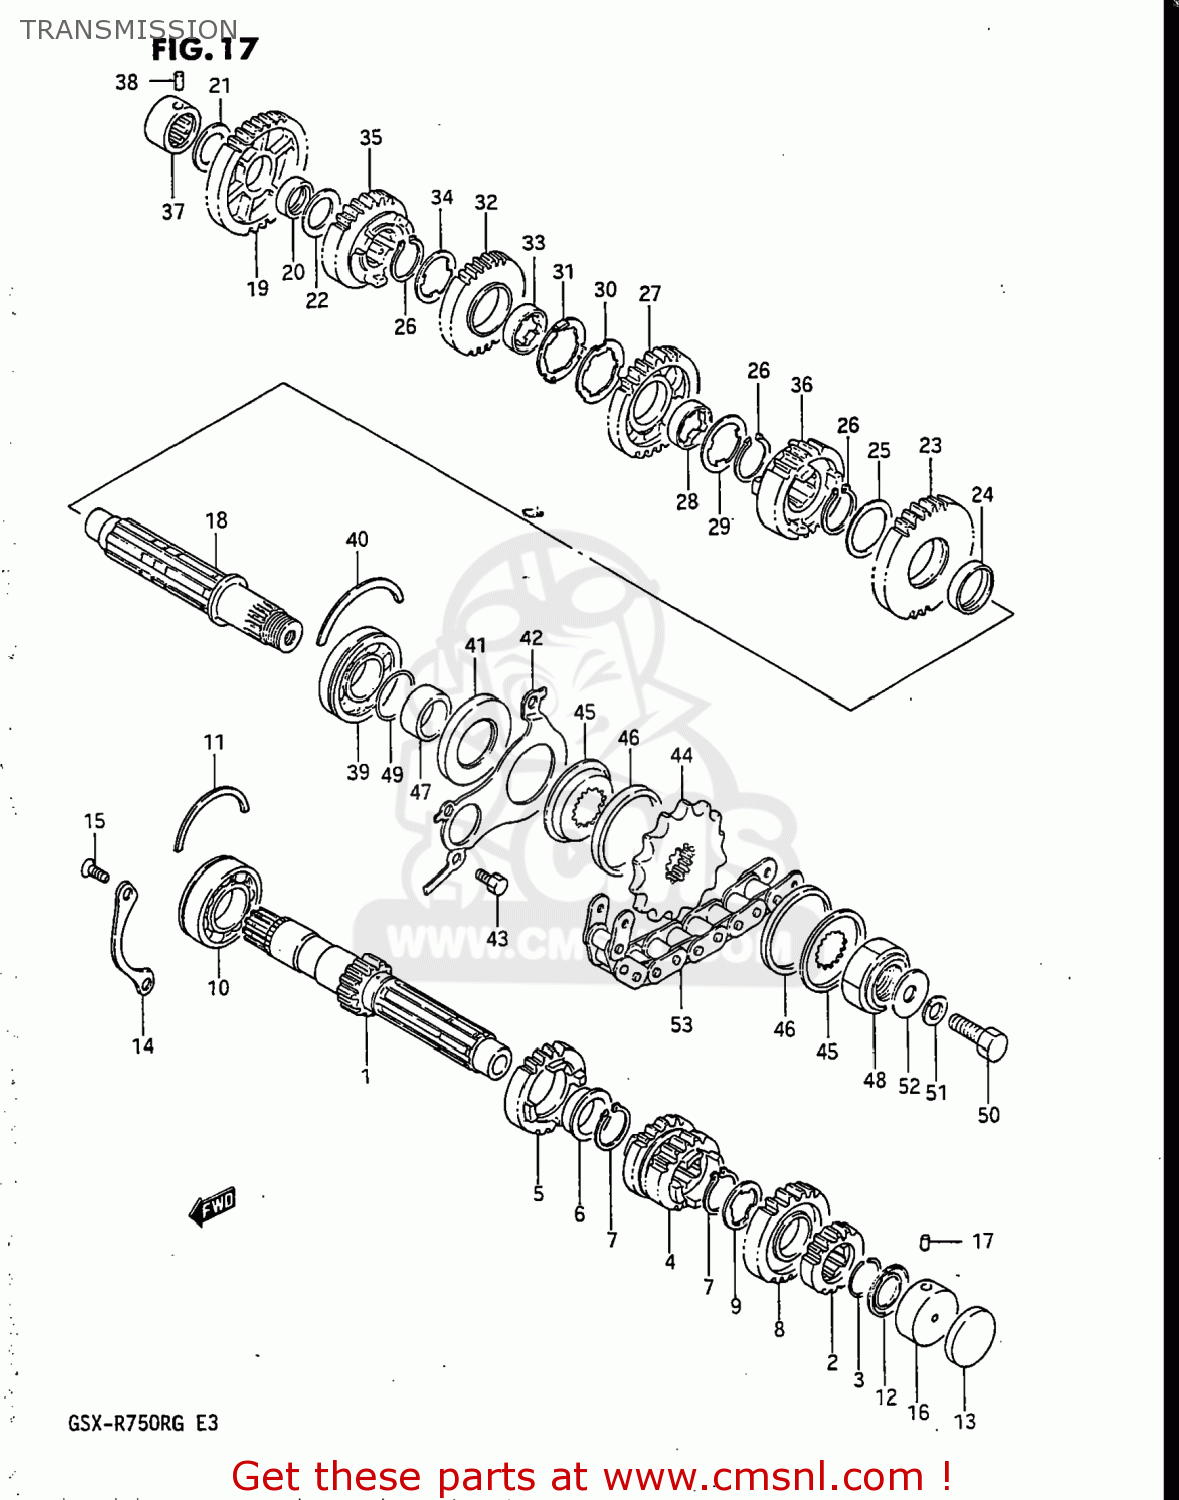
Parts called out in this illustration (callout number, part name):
1	SHAFT,COUNTER
2	GEAR,2ND DRIVE(NT:16)
3	RING,SNAP
4	GEAR,3RD & 4TH DRIVE(NT:17/20)
5	GEAR,5TH DRIVE(NT:22)
6	BUSHING
7	RING,SNAP
8	GEAR,SIXTH DRIVE
9	WASHER,LOCK
10	BEARING(25X62X17)
11	C-RING
12	SEAL,OIL(20X31.2X2.7)
13	CAP,COUNTER SHAFT,L
14	RETAINER,CNTR SHAFT BEARING
15	SCREW
16	BEARING(20X34X17.5)
17	PIN
18	SHAFT,DRIVE
19	GEAR,1ST DRIVEN(NT:36)
20	BUSH(22X26X9)
21	WASHER
22	WASHER
23	GEAR,SECOND DRIVEN
24	BUSH(28X32X8)
25	WASHER, THRUST
26	CIRCLIP
27	GEAR,3RD DRIVEN(NT:28)
28	BUSH
29	WASHER,LOCK
30	WASHER,LOCK
31	WASHER
32	GEAR,FOURTH DRIVEN
33	BUSH
34	WASHER,LOCK
35	GEAR,5TH DRIVEN(NT:27)
36	GEAR,SIXTH DRIVEN
37	BEARING(20X34X20)
38	PIN
39	BALL BEARING 25X62X17
40	C-RING
41	SEAL,OIL(34X62X6)
42	RETAINER,DRIVESHAFT O
43	BOLT
44	SPROCKET,ENGINE
45	HOLDER,SPROCKET DAMPER
46	DAMPER,SPROCKET
47	SPACER (25X34X16.1)
48	NUT
49	O RING(D:1,ID:24.5)
50	BOLT
51	WASHER,LOCK
52	WASHER
53	CHAIN ASSEMBLY,DRIVE
